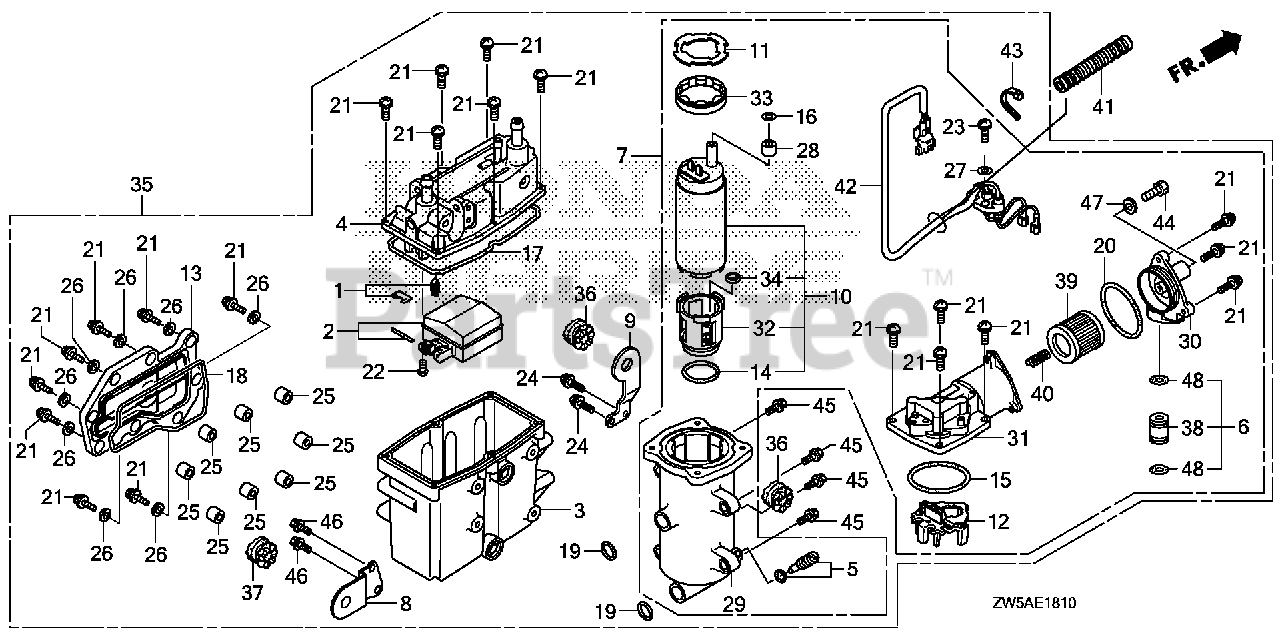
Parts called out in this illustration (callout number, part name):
1	VALVE SET, FLOAT
3	BODY, CHAMBER
4	COVER
5	SCREW SET, DRAIN
7	PUMP UNIT SET A, FUEL (MSDS)
8	STAY, PLATE (A)
9	STAY, PLATE (B)
10	PUMP UNIT, FUEL (B) (MSDS)
13	COVER, WATER JACKET
16	O-RING
21	SCREW-WASHER
22	SCREW, PAN
23	SCREW, WASHER
24	SCREW, WASHER
25	COLLAR, SET
26	WASHER, PLAIN
27	WASHER, PLAIN
29	CASE, PUMP
30	COVER B, PUMP
31	COVER, PUMP (A)
35	SEPARATOR ASSY., VAPOR
35	SEPARATOR ASSY., VAPOR (NOT AVAILABLE)
36	GROMMET, VAPOR SEPARATOR
37	GROMMET, VAPOR SEPARATOR
38	JOINT, FUEL PIPE
39	SCREEN, FUEL STRAINER
40	SPRING, SET
41	TUBE, CORRUGATE (7MM)
44	BOLT, SEALING (6MM)
45	BOLT, FLANGE (6X25)
46	BOLT, FLANGE (6X16)
47	WASHER, SEALING (6MM)
48	O-RING (7.8X1.9) (ARAI)
